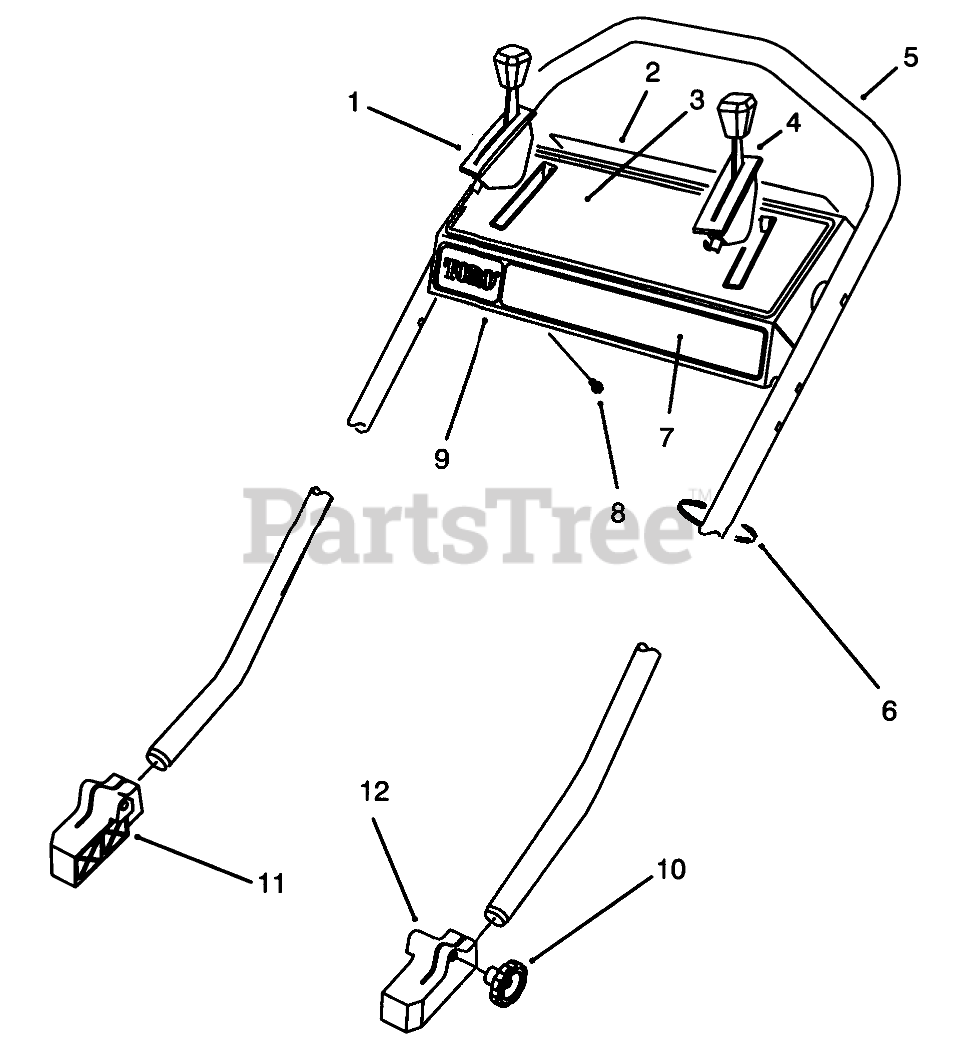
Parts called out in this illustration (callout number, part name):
1	GROUND SPEED CONTROL
2	DECAL - PANEL, REAR
3	DECAL-INSTRUCTION OHV
4	THROTTLE CONTROL
5	HANDLE PVC DIP
6	TIE-CABLE
7	DECAL-PANEL
8	SCREW-HWHTF
9	Control Panel Assembly (Incl. Ref. #2, 3, & 7)
11	MOUNT-HANDLE, RH
12	MOUNT-HANDLE, LH
